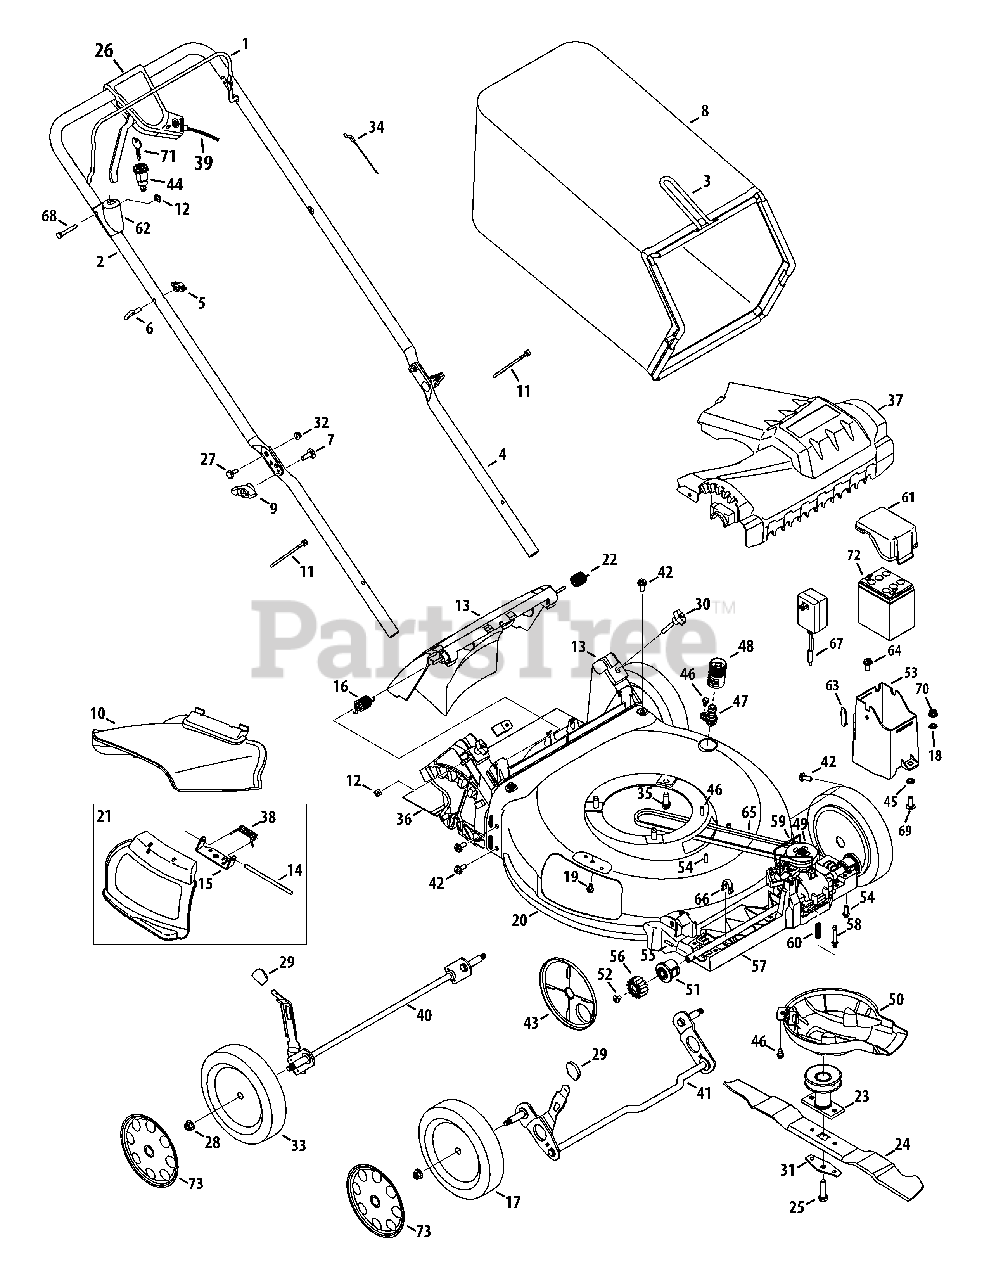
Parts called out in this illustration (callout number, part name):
1	Blade Control
2	Upper Handle
4	Lower Handle
6	Rope Guide
7	Carriage Screw ,5/16-18
8	Grass Bag
10	Side Chute
11	Cable Tie
12	Nut, Sq., 1/4-20
13	Rear Discharge Door Assembly (Lowes model)
13	Rear Discharge Door Assembly
15	Chute Deflector Bracket
16	Torsion Spring - RH
17	Front Wheel
18	Washer, Bell, .340 x .872 x .080
19	Screw, 1/4-20 x .500
20	Deck , 21"
21	Hinged Mulch Plug Assembly
22	Torsion Spring - LH
23	Blade Adapter Assembly
24	Mulching Blade
25	Screw , 3/8-24 x 1.50
26	Control Lever Assembly
27	Sldr. Screw, .375 x .126 x 1/4-20
28	Flange Lock Nut, 3/8-16
29	Adjustment Lever Knob
30	Wing Nut
31	Blade Bell Support
32	Nut, Flange Lock, 1/4-20
33	Rear Wheel
34	Control Cable
35	TT Sems Screw, 3/8-16 x 1.0
36	Trail Shield
37	Front Cover
38	Torsion Spring
39	Drive Cable
40	Rear Axle Assembly
41	Front Axle Assembly
42	Screw, 5/16-14 x .750
43	Wheel Dust Cover
44	Key Switch
45	Speed Nut
46	Screw, Shldr., 1/4-20 x .50
47	Water Nozzle
48	Water Nozzle Adapter
49	Transmission Assembly
50	Engine Baffle
51	Bearing Assembly
52	Screw, 1/4-20 x .390
53	Battery Housing
54	Screw, 1/4-15 x .750
56	Spur Gear, 14T - RH
56	Spur Gear, 14T - LH
57	Lower Tray
58	Spring Body
59	Transmission Wire
60	Compression Spring
61	Battery Housing Top
62	Electric Start Housing
63	Lid Seal
64	Screw, Sldr., 5/16-14 x .972
66	Front Axle Clip
67	Battery Charger
68	Screw, 1/4-20 x 1.75
69	Bolt, Carr., 5/16-18 x 1.00
70	Nut, Flglk., 5/16-18
72	Battery
73	Hubcap, 8"
